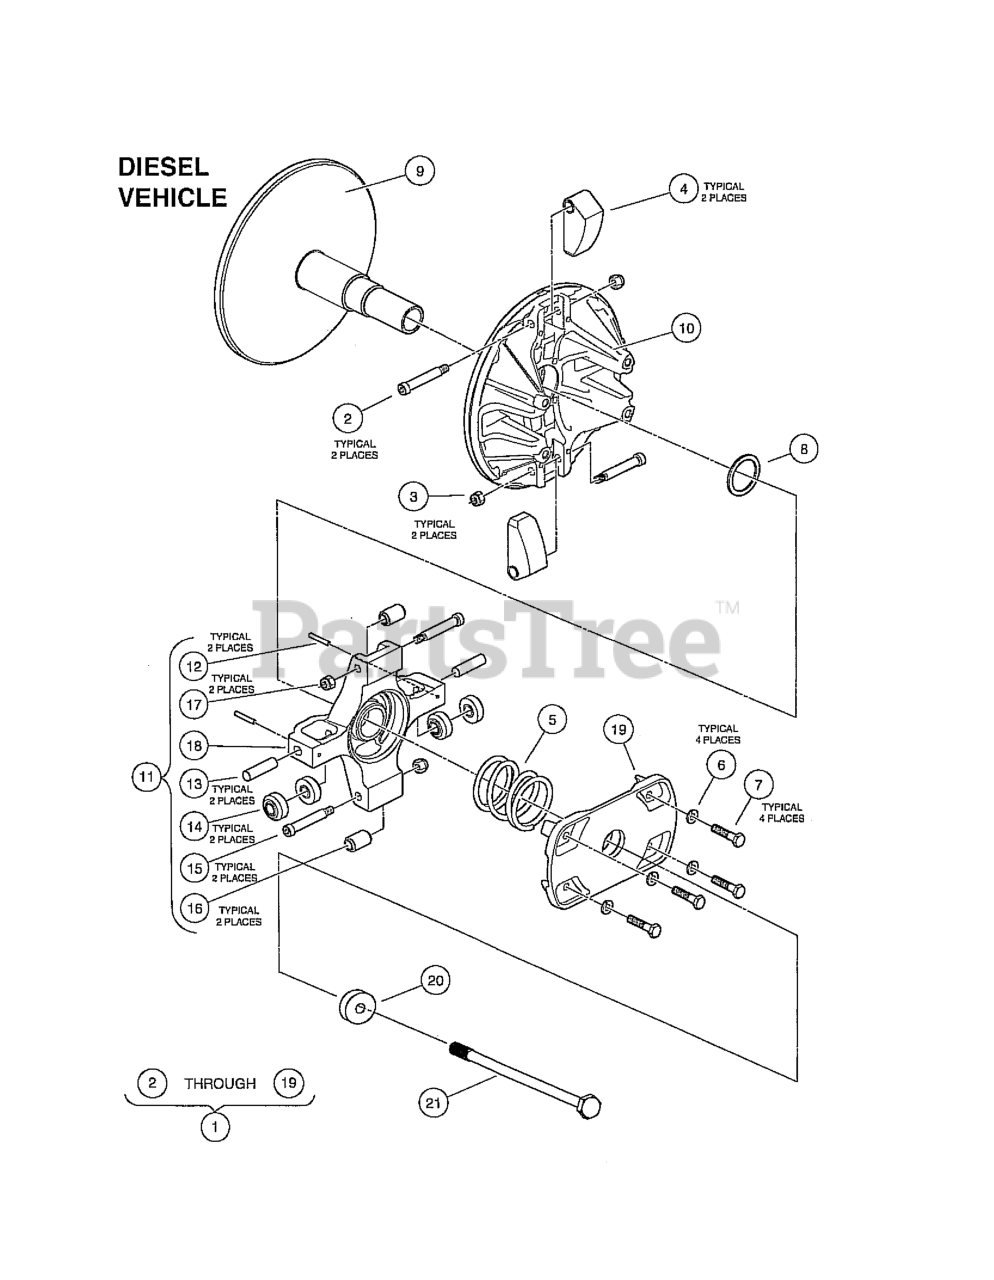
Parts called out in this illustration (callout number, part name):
1	CVT, PRIMARY DIESEL
2	SCREW, SHLDER HEX, .312 X 1.75
3	NUT, LOCK HEX, 1/14-20, FLEXLC
4	SUB ASSY, WT CLUTCH, DIESEL
5	SPRING, COMPRESSION, PRIMARY
6	WASHER, LOCK, H SPRING, 1/4
7	SCREW, CAP, HEX HD, 1/4 X 1.25
8	SHIM, 1.63 X 1.33
12	PIN, SPRING SLOTTED,1.25 X 1.0
13	PIN, DOWEL, .375 X 1.50
14	ROLLER, TORQUE, DIESEL
15	SCREW, SHLDER HEX, .312 X 1.75
16	SUB ASSY, ROLLER WEIGHT
17	NUT, LOCK HEX, 1/14-20, FLEXLC
20	WASHER, STEPPED, CVT PRIMARY
21	BOLT, M10X1.5X160
